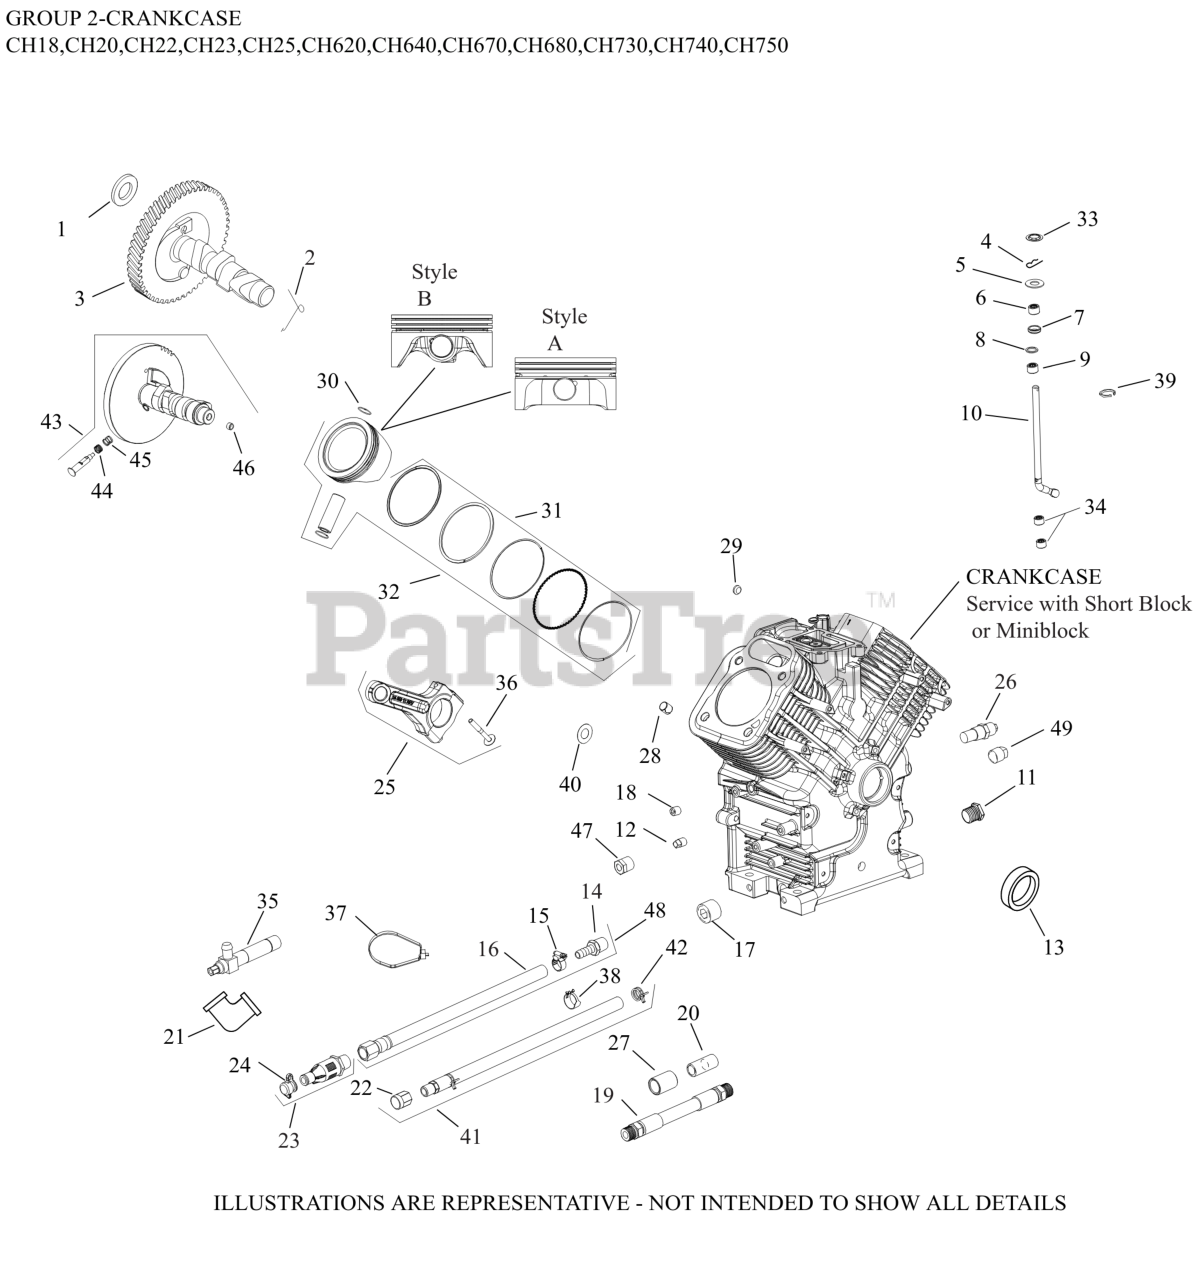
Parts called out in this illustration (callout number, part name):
3	KIT, CAMSHAFT-(#2401223S)
5	WASHER, FLAT 9 MM
7	SEAL, GOVERNOR CROSS SHAFT
8	WASHER, FLAT 11/32"
10	SHAFT, GOVERNOR CROSS
11	PLUG, HD PIPE 3/8"
13	SEAL, OIL (HELIX LIP)
18	PLUG, PIPE CTSK 3/8"
25	ROD, ASSEMBLY CONNECTING
27	COUPLING, PIPE
28	PIN, LOCATING
29	PLUG, CUP
30	RETAINER, PISTON PIN
31	RING SET (STD)-(#DSC)
31	RING SET (.08)-DISCONTINUED
31	RING SET-DISC. USE PISTON ASSY PER SPEC
31	RING SET (.50)-(#DSC)
32	KIT,PISTON ASSY W/RING(STD)77MM
32	KIT,PISTON W/RING SET(.08)77MM-DISC.
32	KIT,PISTON ASSY W/RING SET(.25)-(#DSC)
32	KIT,PISTN ASSY W/RING SET(.5)77MM-(#DSC)
33	RETAINER, RING
36	KIT, ROD BOLTS-(#25086677S)
NI	PIPE NIPPLE 3/8" X 1.5
